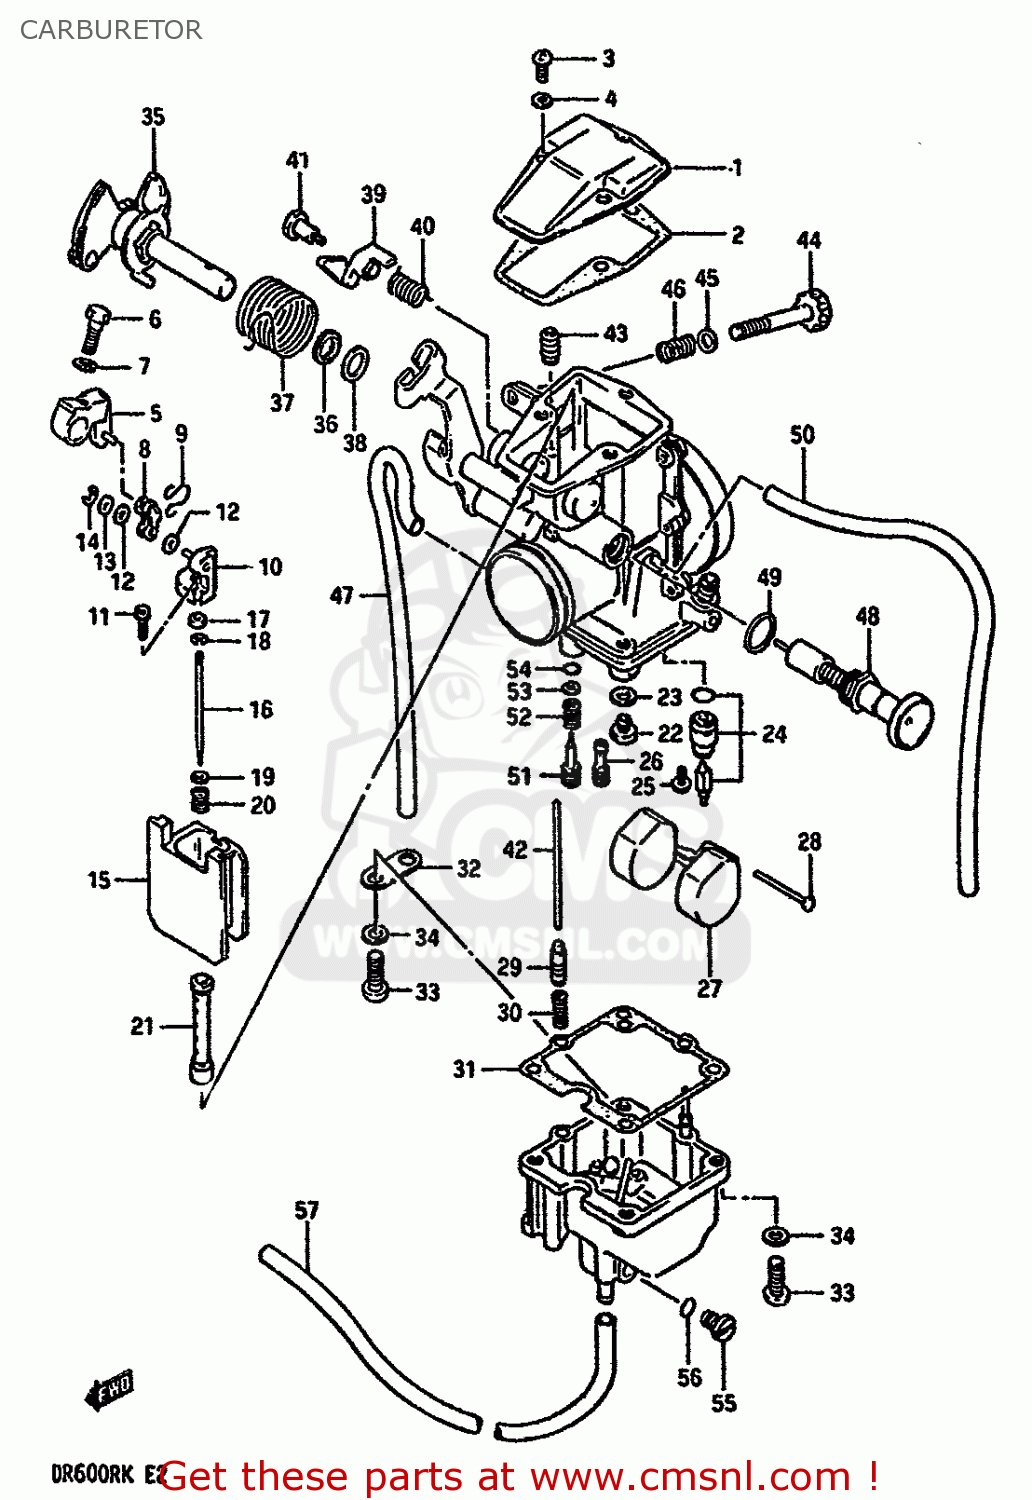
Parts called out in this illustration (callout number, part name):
1	CAP, TOP
2	GASKET,CARBURETOR TOP (NAS)
3	SCREWM4X0.7X10
4	LOCK WASHER
5	ARM,THROTTLE
6	BOLT
7	LOCK WASHER
8	PLATE
9	SPRING
10	BRACKET
11	SCREW
12	GASKET (NAS)
13	WASHER
14	E-RING
15	VALVE,THROTTLE
16	NEEDLE,JET
17	RING
18	CLIP
19	WASHER,JET NEEDLE
20	SPRING
21	JET,NEEDLE(O-0)
22	JET,MAIN(135)
23	WASHER,NEEDLE NOZZLE
24	VALVE ASSY,NEE
25	SCREW
26	JET,PILOT 20
27	FLOAT
28	PIN,FLOAT
29	PLUNGER
30	SPRING
31	GASKET,FLOAT CHAMBER (NAS)
32	PLATE
33	SCREW
34	LOCK WASHER
35	SHAFT ASSY
36	SEAL
37	SPRING
38	RING,THROTTLE SHAFT
39	LEVER
40	SPRING
41	BOLT
42	ROD,PLUNGER
43	BOOT, ACCELE PUMP ROD
44	SCREW,THROTTLE STOP
45	WASHER
46	SPRING
47	HOSE (3.5X6.5X200)
48	PLANGER ASSY
49	O RING
50	HOSE
51	SCREW,PILOT
52	SPRING
53	WASHER
54	O RING,PILOT AIR SCREW
55	PLUG
56	GASKET,DRAIN,PLUG (NAS)
57	HOSE
